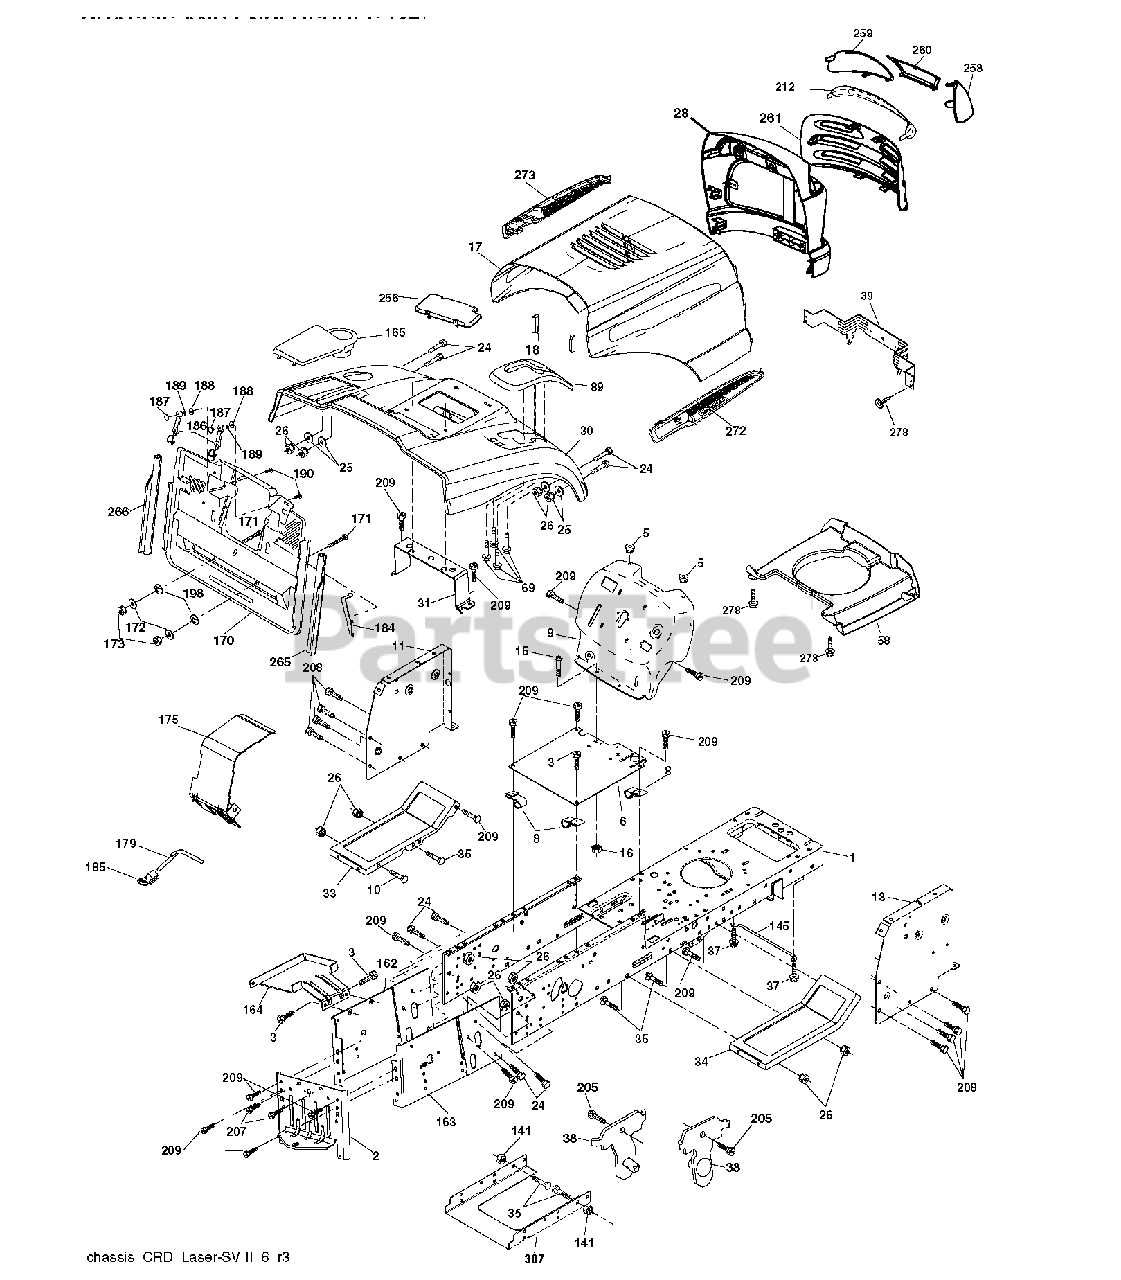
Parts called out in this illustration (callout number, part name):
1	CHASSIS
3	SCREW 3/8-16X3/4
5	BUMPER.RUBBER.HOOD
8	CLIP,INSULATOR
10	BOLT D
11	PANEL.DASH.LH.LTX
13	PANEL ASM, DASH RH
16	NUT
18	BUMPER.HOOD.LARGE.1.75"
25	WASHER
26	NUT
31	BRACKET SUPPORT FENDER
39	BRACKET PIVOT
69	SCREW.HI-LO.CONSOLE
141	NUT LOCK FLG 3/8-16 UNC
145	ROD.PIVOT.HOOD
164	SUPPORT
171	BOLT
172	WASHER
186	LATCH ASSY
187	WELDNUT
189	LOCKWASHER
207	SCREW, 5/16-18 X 1/2
208	SCREW 3/8-16X1/2
209	SCREW, 3/8-16X3/4
278	SCREW.#10 X 0.750.BOS THREAD
